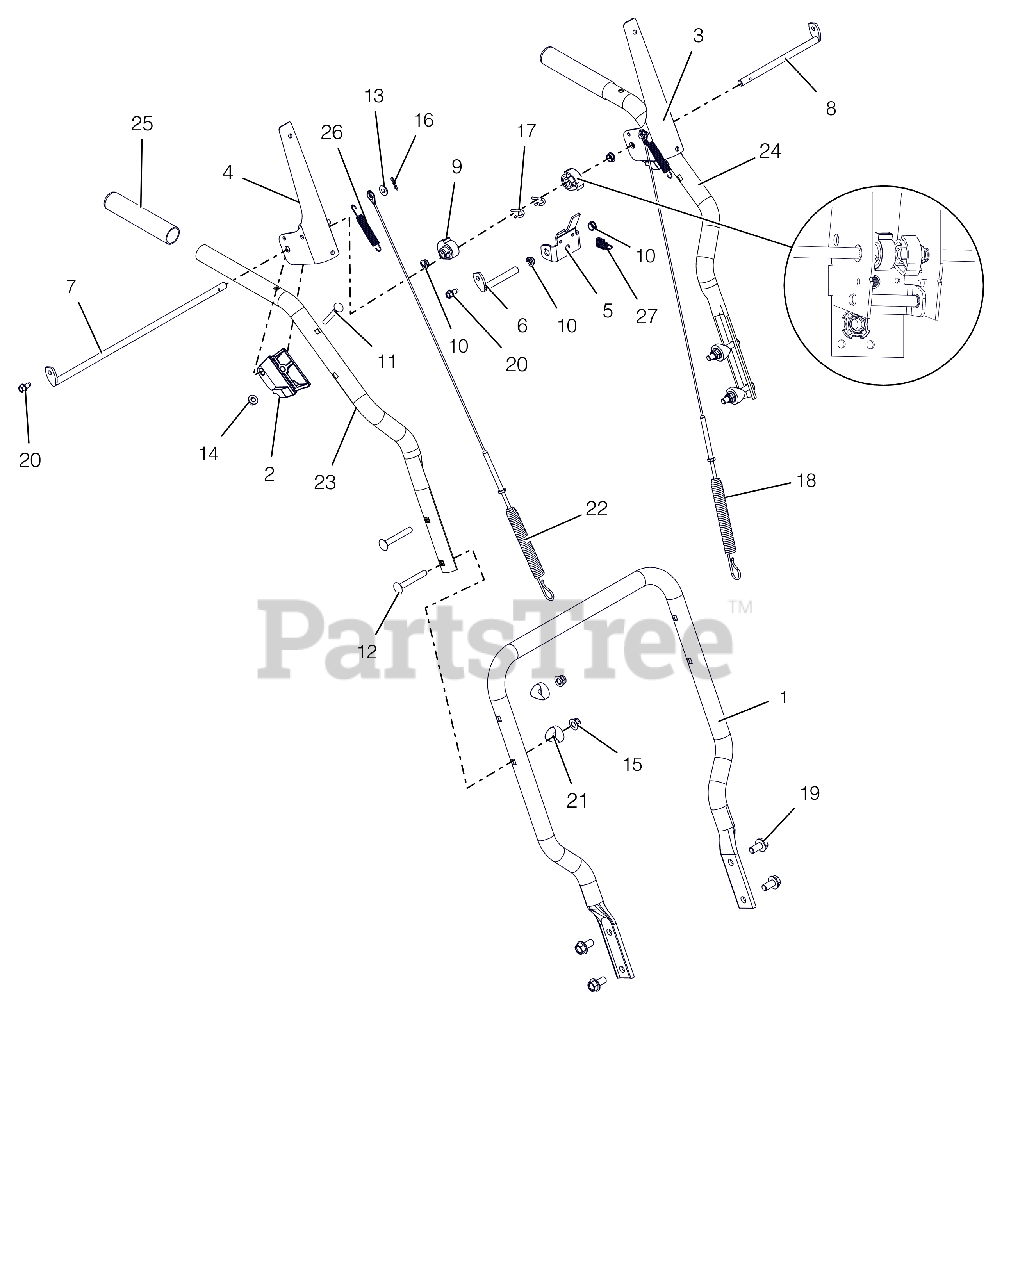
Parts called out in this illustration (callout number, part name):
1	HANDLEBAR, LOWER (COMPACT)
2	BLOCK, CLUTCH PADDLE
3	LEVER, CLUTCH-LH
4	LEVER, CLUTCH-RH
5	BRACKET, INTERLOCK ARM
6	ROD, PIVOT - INTERLOCK
7	ROD, PADDLE MOUNT - LONG
8	ROD, PADDLE MOUNT - SHORT
9	CAM, INTERLOCK
10	BUSHING, POLYLINER-.38 SNAPIN
11	BLT-RDHDXLSQNK .25-20X2.0 G5YZ
12	@BLT-RDHDSQNK .31-18X2.25 G5YZ
13	@WSHR-FL-STL.281X.62X.065 YWZC
14	@NUT-LK-TOP-FLG .25-20 YWZC
15	@NUT-LK-NYL-FLG .31-18 YWZC
16	PIN-HAIR INT .06X.18X.77
17	PIN, SPRING CLIP
18	CABLE, AUGER & UPPER TRACTION
19	BLT-SERHFWH .38-16X.75 YWZC
20	SCR-TAP .25-20X.50 HWH TR YWZ
21	SPACER, HANDLEBAR
22	CABLE, AUGER & UPPER TRACTION
23	HANDLEBAR, UPPER - RH
24	HANDLEBAR, UPPER - LH
25	GRIP,HANDLE-GRAY
26	SPRING, EXTENSION
27	SPRING-EXT .047X.438X1.45
